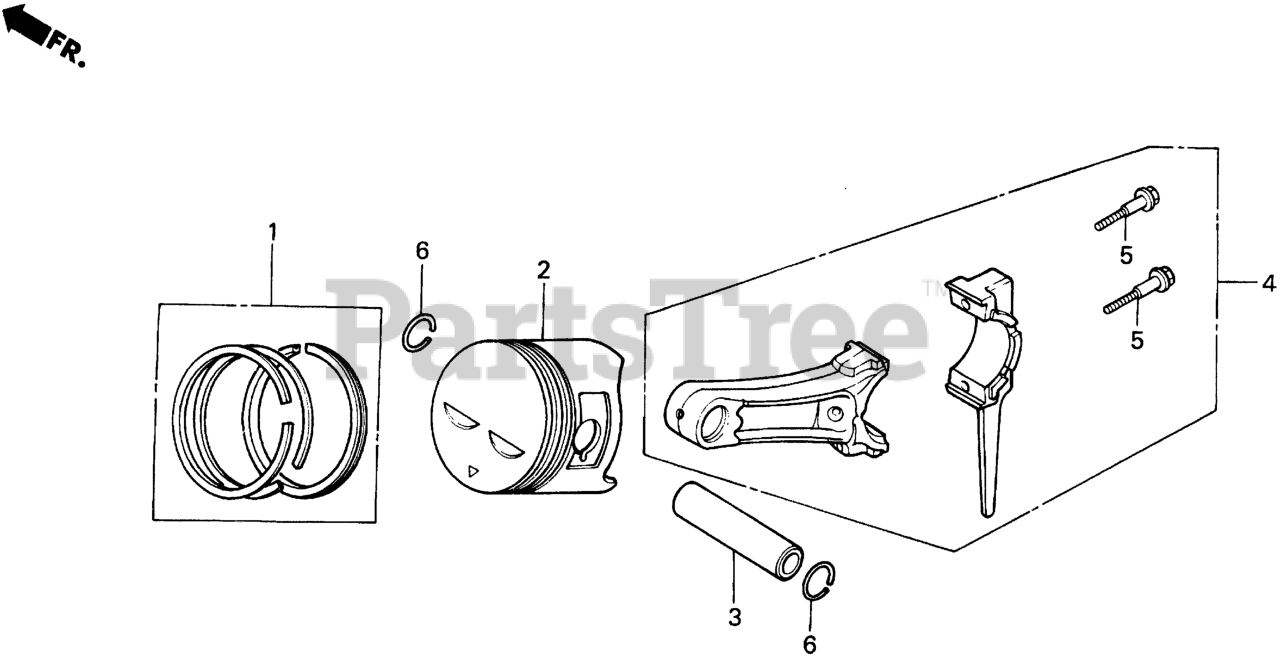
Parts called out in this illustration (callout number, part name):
1	RING SET, PISTON (STD)
1	RING SET, PISTON (STD) (NIPPON)
1	RING SET, PISTON (STD) (TEIKOKU)
1	RING SET, PISTON (OS 0.25) Use up to Engine SN 2623677.
1	RING SET, PISTON (OS 0.25) Use up to Engine SN 1281053.
1	RING SET, PISTON (0.25) (NIPPON) Use up to Engine SN 4081304.
1	RING SET, PISTON (OS 0.25) Use up to Engine SN 4081304.
1	RING SET, PISTON (OS 0.50) Use up to Engine SN 2623677.
1	RING SET, PISTON (OS 0.50) Use up to Engine SN 1281053.
1	RING SET, PISTON (OS 0.50) Use from Engine SN 4081305.
1	RING SET, PISTON (OS 0.75) Use up to Engine SN 1242764.
1	RING SET, PISTON (OS 0.75) Use up to Engine SN 1281053.
1	RING SET, PISTON (0.75) (NIPPON) Use up to Engine SN 4081304.
1	RING SET, PISTON (0.75)
2	PISTON (STD)
2	PISTON (OS 0.25)
2	PISTON (0.50)
2	PISTON (OS 0.50)
2	PISTON (OS 0.75) Use up to Engine SN 1263002.
2	PISTON (OS 0.75)
3	PIN, PISTON
4	ROD ASSY., CONNECTING (STD)
4	ROD ASSY., CONNECTING (Honda Code 2110153). (US 0.25)
5	BOLT, CONNECTING ROD
6	CLIP, PISTON PIN (18MM)
